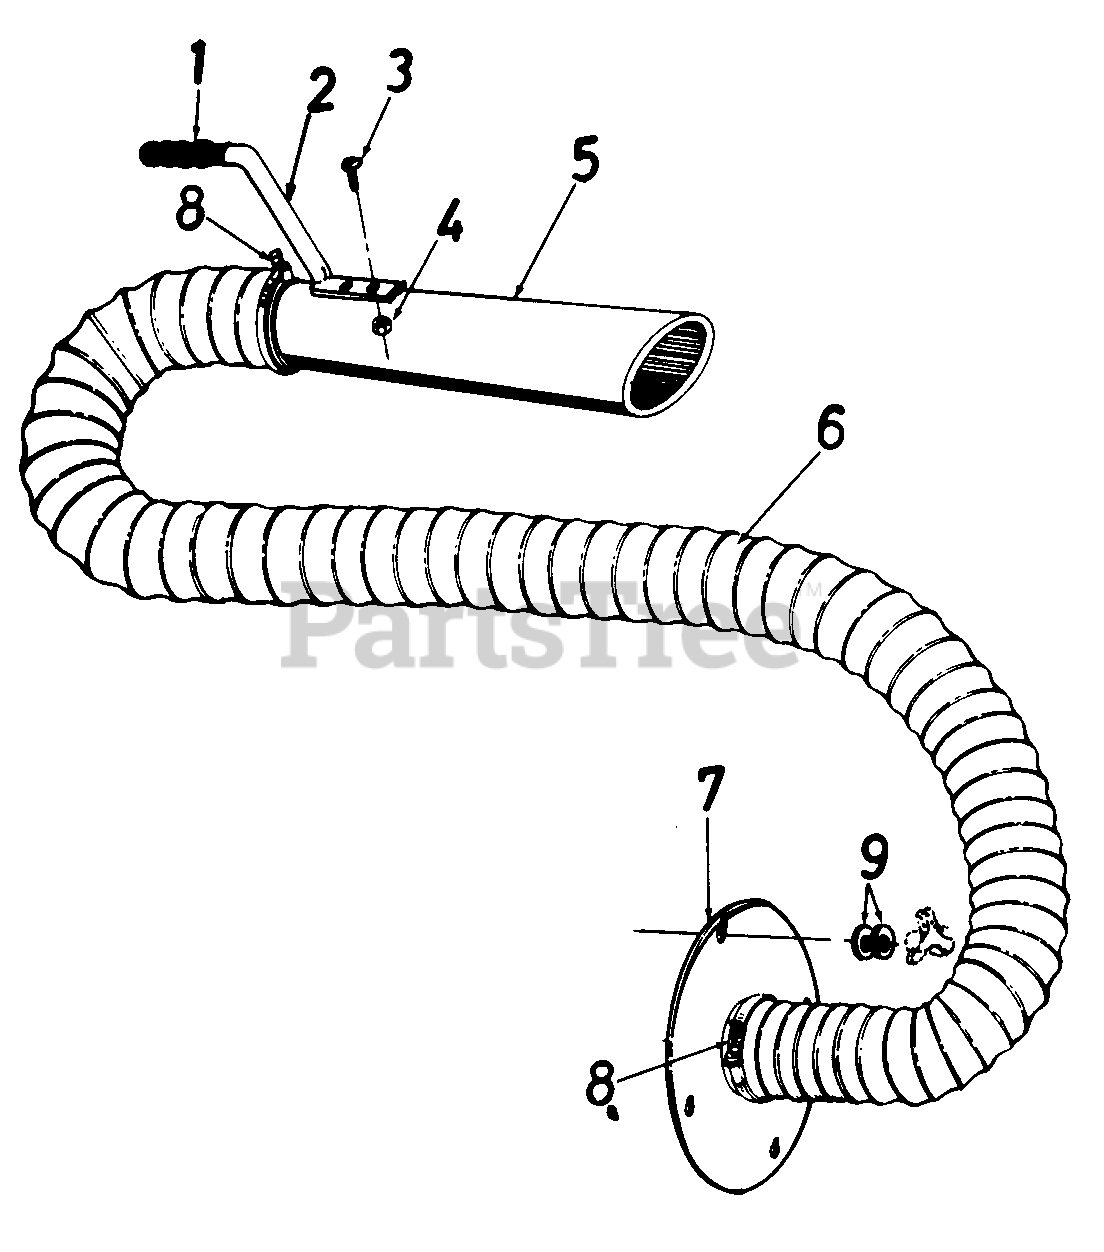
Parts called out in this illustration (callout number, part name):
1	Handle Grip
2	Handle
3	Truss Sems Scr. 10-24 x 1/2" Lg.
4	Hex Nut 10-24 Thd.
5	Hose Nozzle
6	Flexible Hose 4" Dia. x 10' Lg.
9	Flat Washer .34 I.D. x 1.12 O.D.
